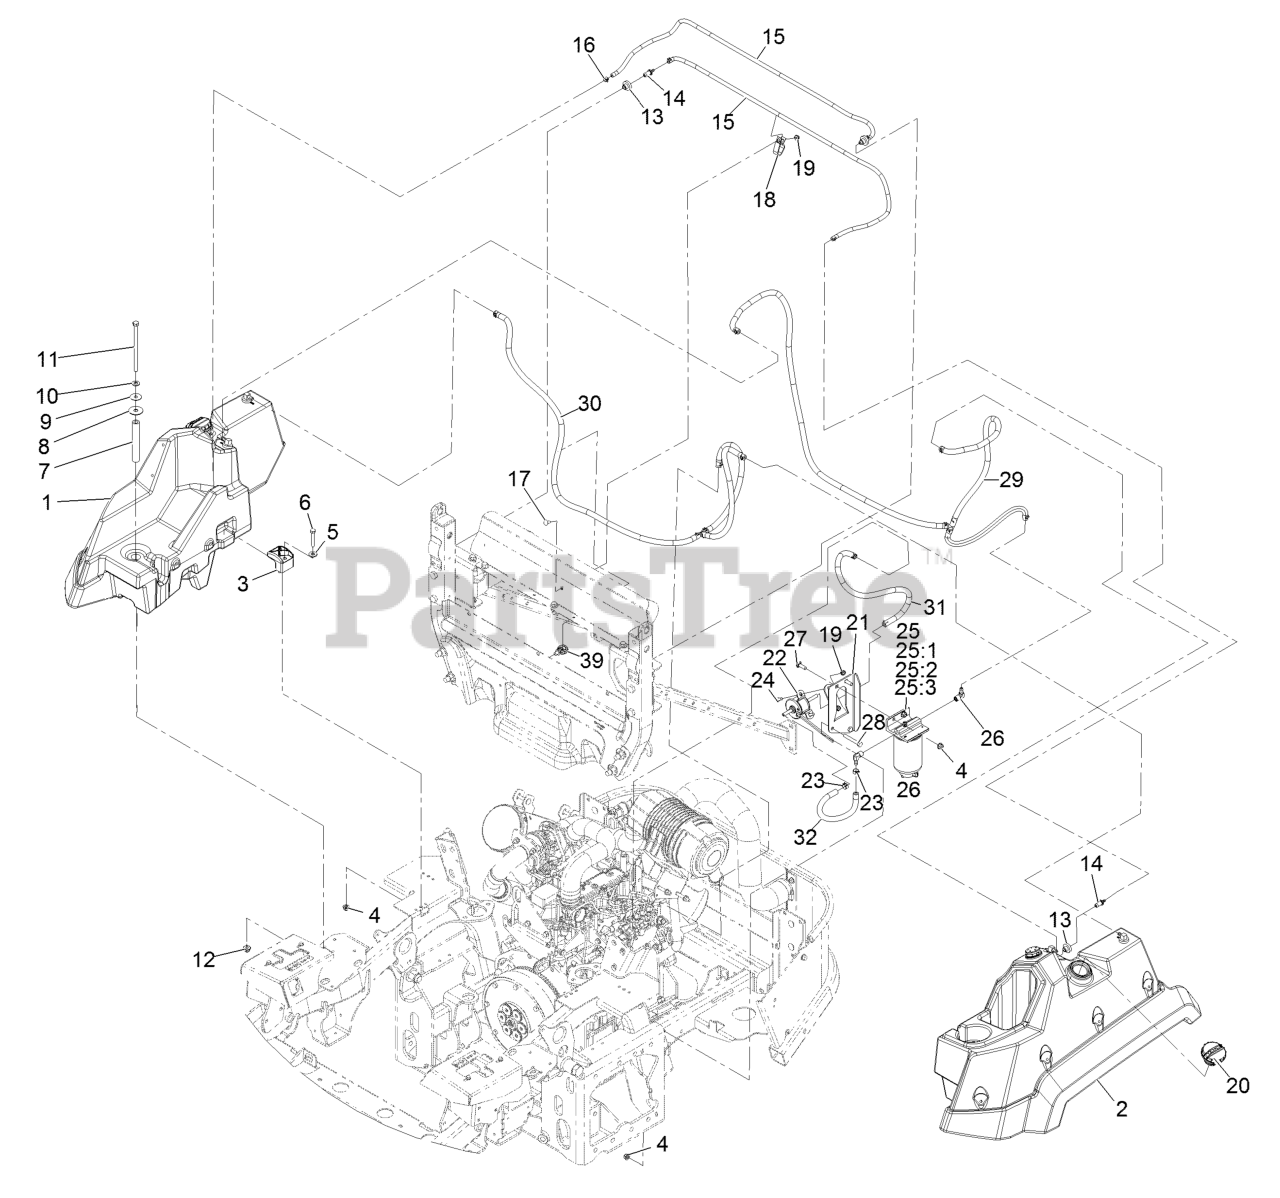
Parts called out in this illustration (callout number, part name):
1	RH Fuel Tank ASM
2	LH Fuel Tank ASM
4	Nut-Nyloc 5/16-18 Flg
5	Washer-5/16 Std
6	Screw-HH
7	Tube-Spacer
8	Washer-Rubber
9	Washer-Plain
10	Washer-3/8 SAE
11	Screw-HH
12	Nut-Nyloc 3/8-16 Flg
13	Bushing
14	Fitting-Orifice, Straight
15	Hose-Vent, Tank
16	Clamp-Hose
17	Bolt-Carriage 1/4-20 X 5/8
18	Clamp-Hose
19	Nut-Nyloc 1/4-20 Flg
20	Cap-Fuel, Diesel
21	Bracket-Filter & Pump, Fuel
22	Pump-Fuel, Electric
23	Clamp-Hose
24	Screw-Machine 1/4-20 X 3/4
25	Separator-Filter
25	ASM,Fuel Filter
25:1	Filter-Spin On
25:2	Filter,Fuel
25:3	Decal,Exmark Filter
26	Fitting-Elb, 90
27	Bolt-Carriage 5/16-18 X 1 Sp
28	Screw-HH 5/16-18 X 2 1/4
29	ASM-Fuel Line, Suction
30	ASM-Fuel Line, Return
31	Hose-Fuel
32	Hose-Fuel
39	Clip-Tie
